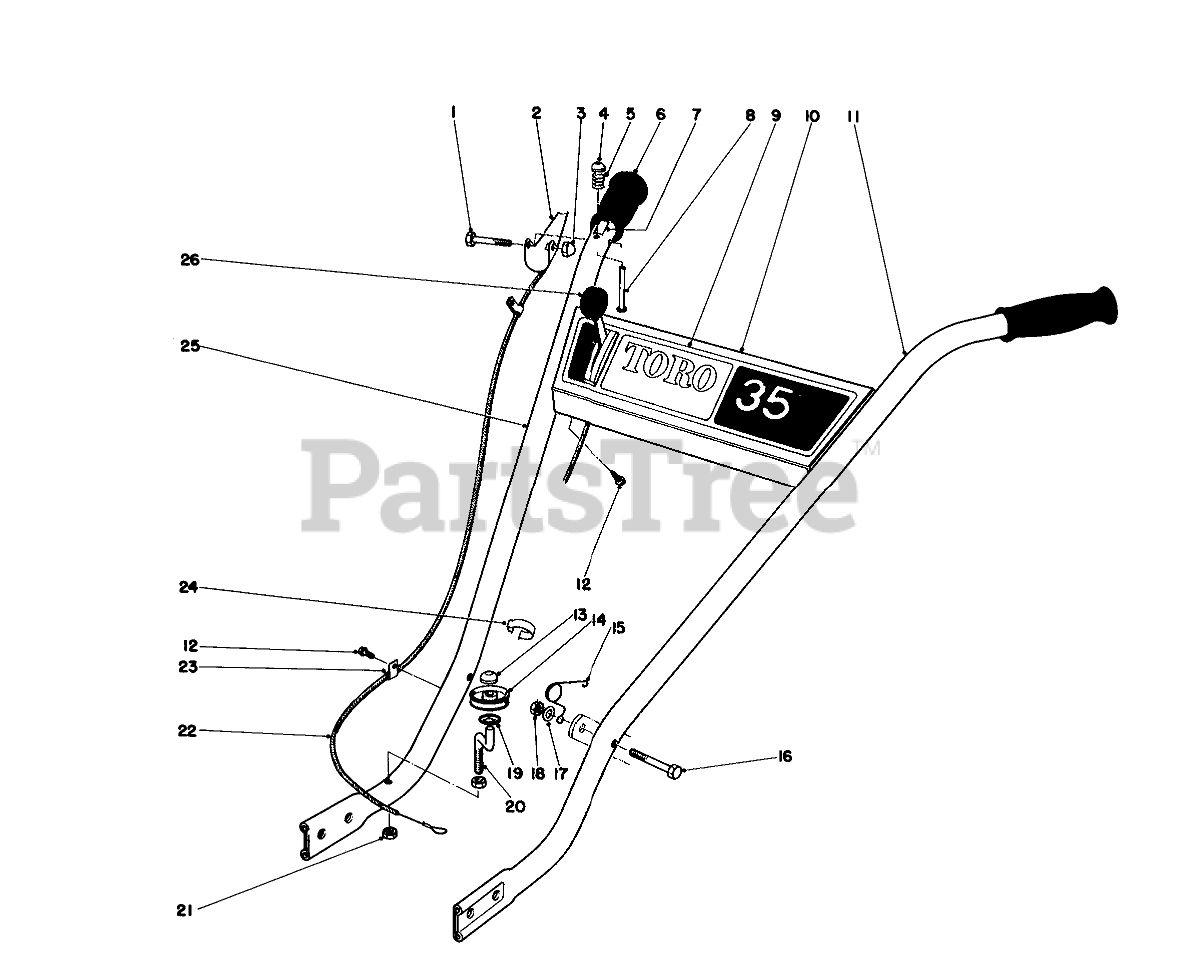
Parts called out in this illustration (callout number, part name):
1	SCREW-HH
2	LIFTBAIL
3	NUT-CAP
4	Push-On
5	COMPRESSION SPRING
6	Hand Grip
7	Decal-Fwd.
8	LOCK PIN
9	Decal-Escutcheon
10	Escutcheon Panel
11	L.H. Handle
12	SCREW-HWHTF
13	RETAINER PUSH ON
14	Pulley Cable
15	Spring-Torsion
16	SCREW-HH
17	WASHER-PLAIN
18	NUT-LOCK, CONE
19	PUSH ON RETAINER
20	Spindle-Fwd.
21	LOCKNUT
22	FWD CABLE ASM
23	3/16 SUPPORT
24	Boden Clip
25	RH HANDLE
26	Throttle Control
